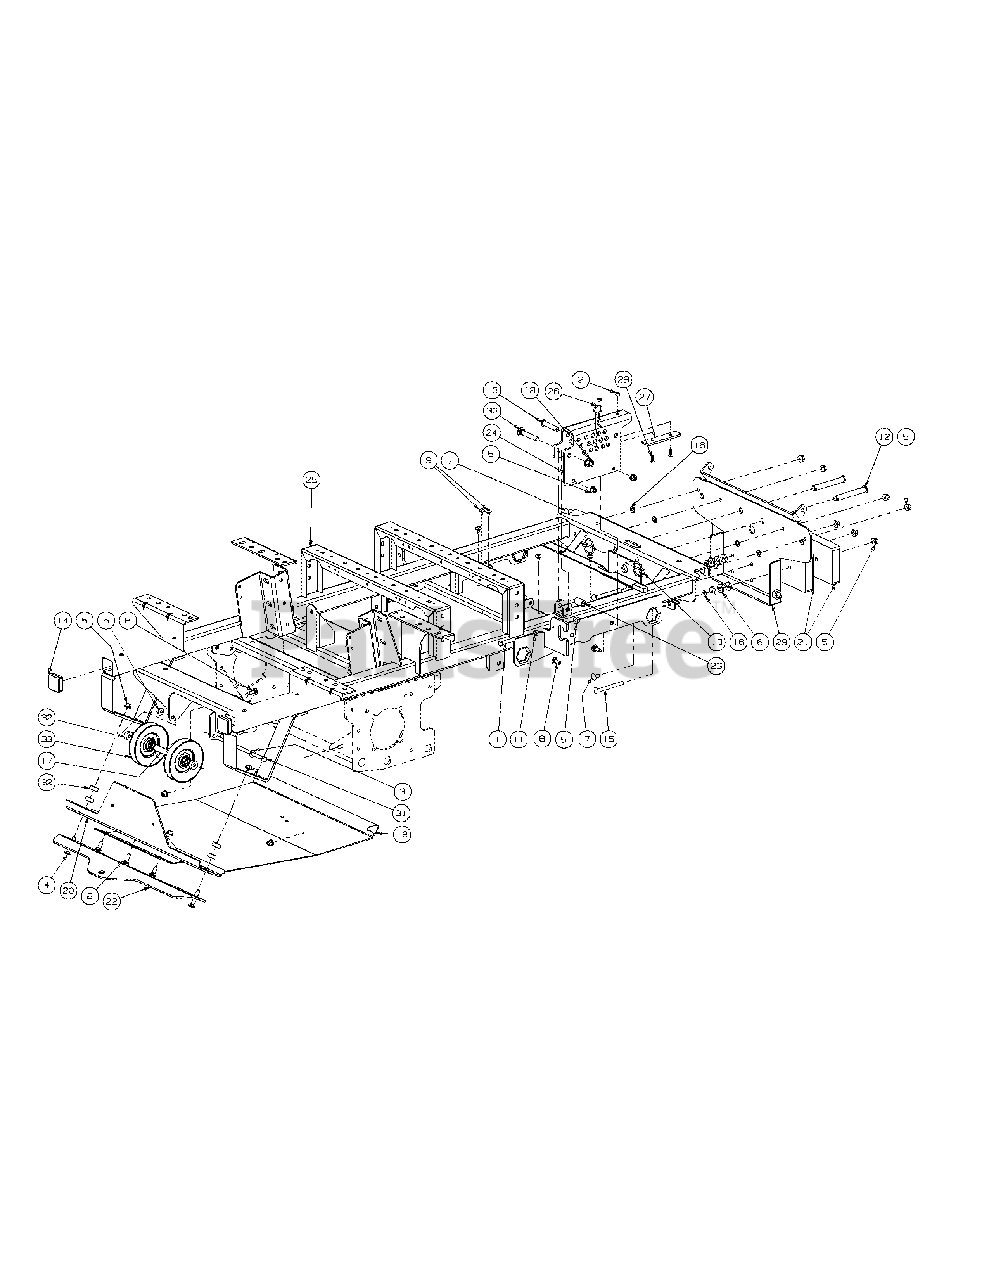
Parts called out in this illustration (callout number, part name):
1	Hex Cap Screw 3/8-16 x 2.00
2	Lock Nut w/Nylon Insert
3	Flat Washer, 3/8
4	Carriage Bolt, 3/8-16 x 2.00
5	Hex Nut, 3/8-16 Flange Lock
6	Idler Washer
7	Carriage Bolt, 3/8-16 x .75 Long
8	Carriage Bolt, 3/8-16 x 1
9	Rubber Bumper, .62 OD x .22 Thick
10	Clevis Pin, .500 Dia. x 2.50 Lg.
11	Nut, 3/8-16, Jam
12	Clevis Pin, .625 Dia x 4.375 Long
13	Linch Pin, 3/16 Dia.
14	Plug, Square Tube
15	Carriage Bolt, 3/8-16 x 4.0
16	Push Retainer, 3/8"-Thread Stud
17	Spacer, .385 ID x .625 OD x 4.89
18	Nut, 1/2-13, Flangelock
20	Guard Bracket
23	Spacer, .51 ID x .75 OD x 1.40
24	Lift Index Bracket
25	Frame Assembly
26	HitchPin, .120 Dia. x 3.0
27	Wear Plate, 1.125 x 5.00
28	Flat Head Cap Screw, 1/4-20 x .75
29	Front Frame Bracket Assembly
30	Carriage Bolt, 1/2-13 x 3.00
31	Hex Head Cap Screw, 3/8-16 x 8.50
32	Spacer .406 ID x 1.0 OD
33	Idler Pulley, 5.06 Dia.
